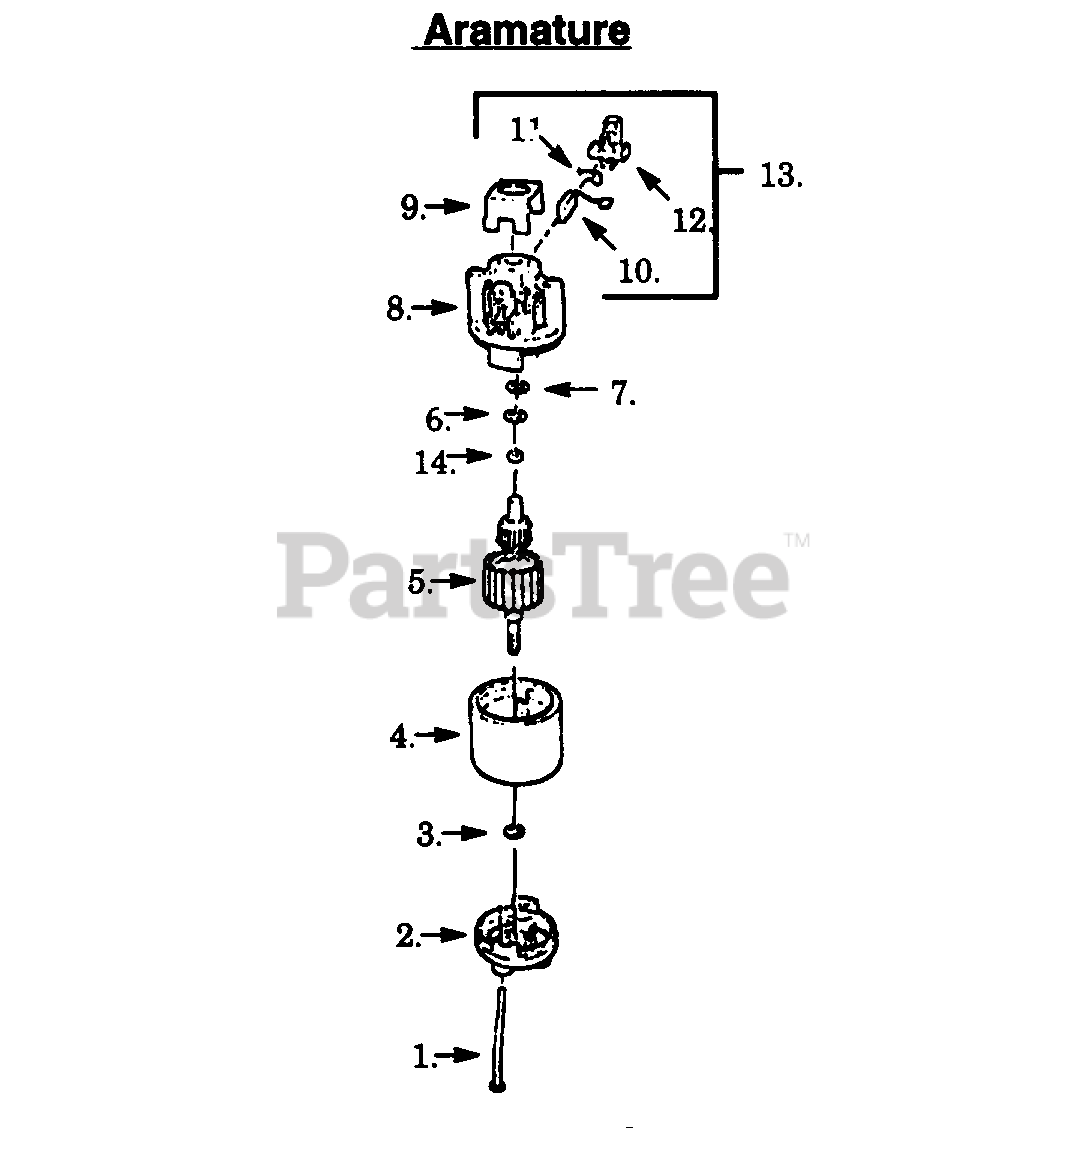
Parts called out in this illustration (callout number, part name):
2	Endbell Ass'y. (Drive)
4	Field Ass'y., E125BT
4	Field Ass'y., E150BT
5	Armature Ass'y., E125BT E150BT
5	Armature Ass'y., Type 1
5	Armature Ass'y., Type 2
8	Endbell Ass'y. (Brush)
9	Insulator
10	Carbon Brush
11	Brush Spring
12	Brush Holder
13	Brush Kit
14	Retaining Ring
